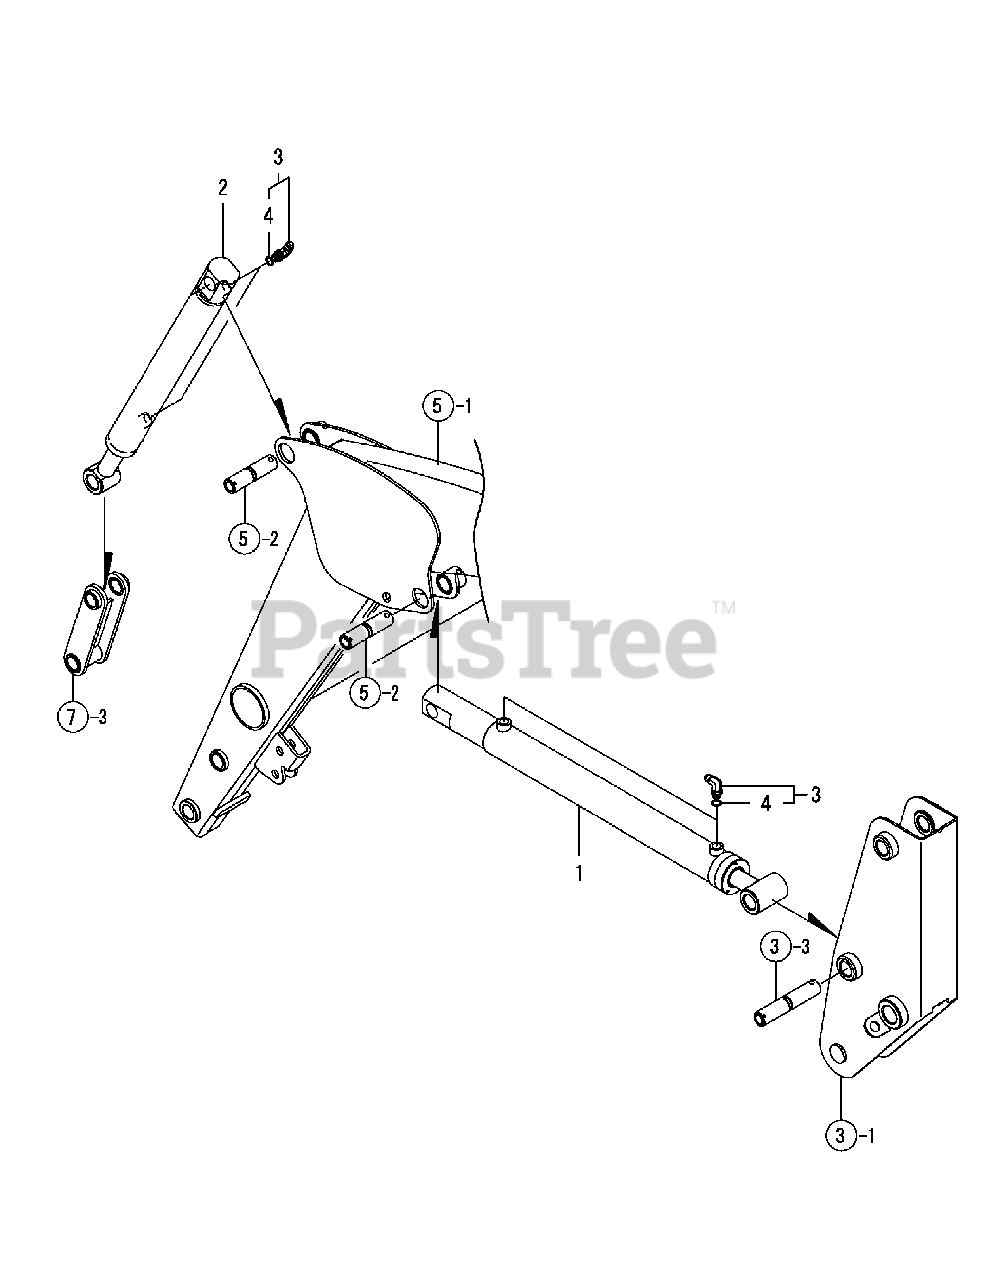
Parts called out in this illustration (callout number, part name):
1	LIFT CYLINDER ASSY
2	DUMP CYLINDER ASSY
3	JOINT,90SAE9/16-18
4	PACKING, JOINT
